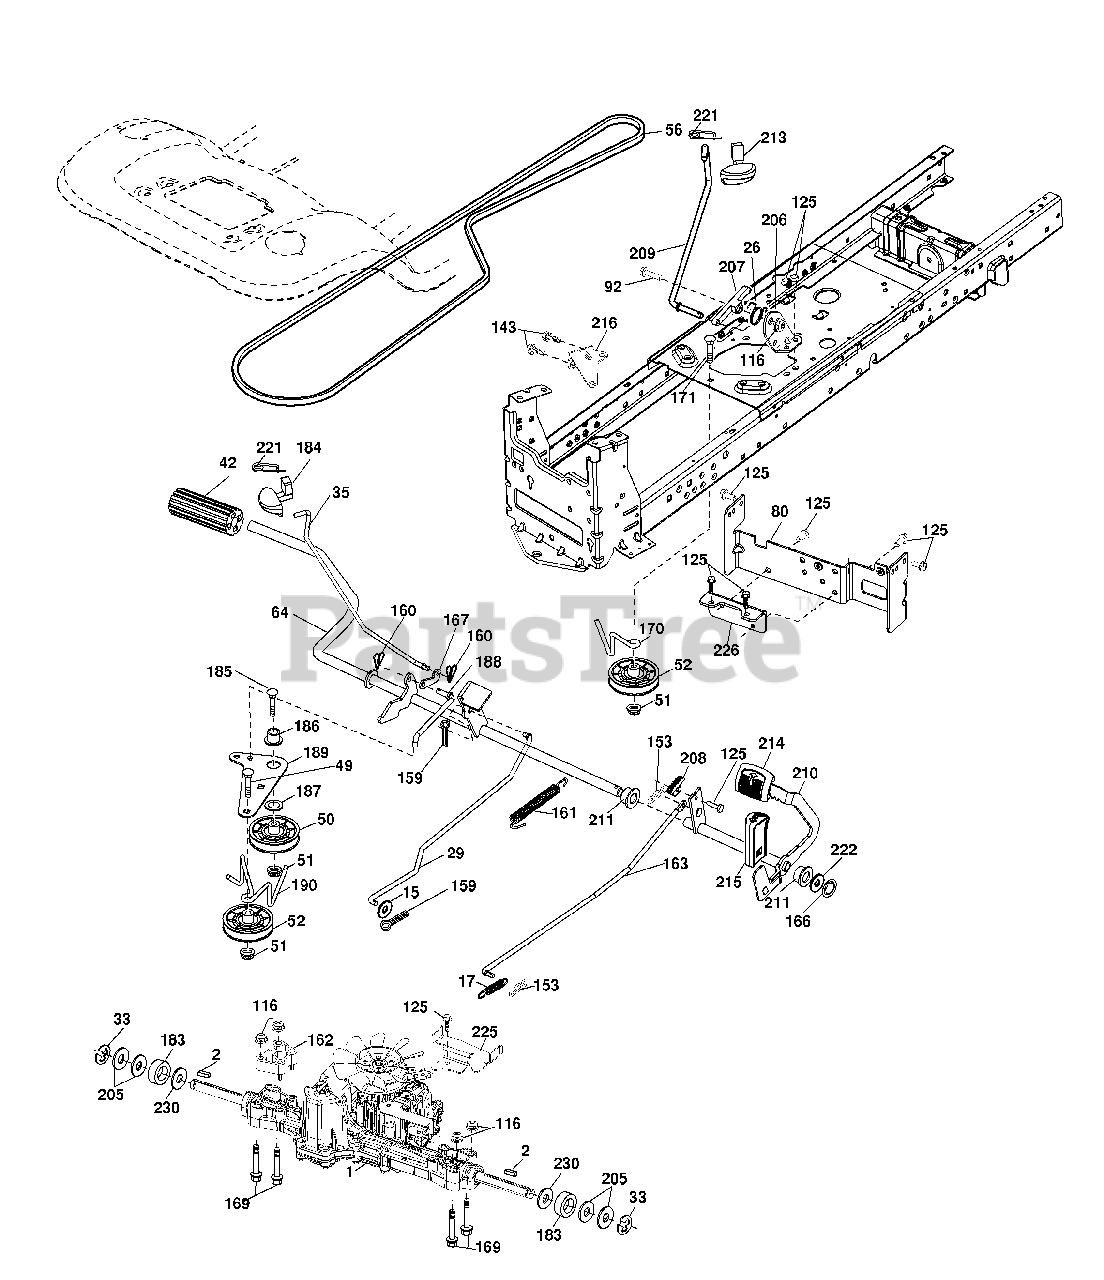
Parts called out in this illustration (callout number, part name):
2	Key Square
15	Washer 13/32 x 13/16 x 16 Ga.
17	Spring, Brake
26	Spring Return Cruise
29	Rod, Brake
35	Rod, Brake, Park
42	Cover, Foot Pedal
50	Pulley Idler Flat
51	Lock Nut 3/8-16
52	Idler V-Groove 910" Offset
56	V-Belt, Drive
64	Shaft Asm. Pedal Brake Control
80	Strap Torque
92	Bolt Fin Hex 5/16-18 unc x 1.25
116	Nut Lock Hex Flange 5/16-18
125	Screw 5/16-18 x 3/4
143	Screw 5/16-18 x 1/2
153	Retainer Spring
159	Pin Cotter 1/8 x 3/4
160	Retainer Clip
161	Spring, Return, Clutch
162	Spacer Transaxle
163	Rod Pedal Control
166	Nut Push
167	Latch Brake Parking
169	Bolt Hex 5/16-18 x 3.75
170	Keeper Belt Centerspan
183	Spacer Axle
184	Handle Parking Brake
186	Spacer Retainer
187	Washer
188	Link Clutch Ground Drive
189	Bellcrank Ground Drive
190	Keeper Bellcrank Ground Drive
205	Washer 25/32 x 1-5/8 16 Ga.
206	Bracket Mount Latch Cruise
207	Latch Control Cruise
208	Gear Sector Control Cruise
209	Rod Control Cruise
210	Rockr Asm. Pedal Control
211	Bearing Nylon
213	Knob control Cruise
214	Pad Pedal Forward
215	Pad Pedal Reverse
216	Bracket Pulley Idler
221	Retainer Spring Clip
222	Washer 21/32 x 1-1/4 10 Ga.
225	Keeper Bolt Transaxle
226	Bracket Mount Torque
230	Washer Hardened
